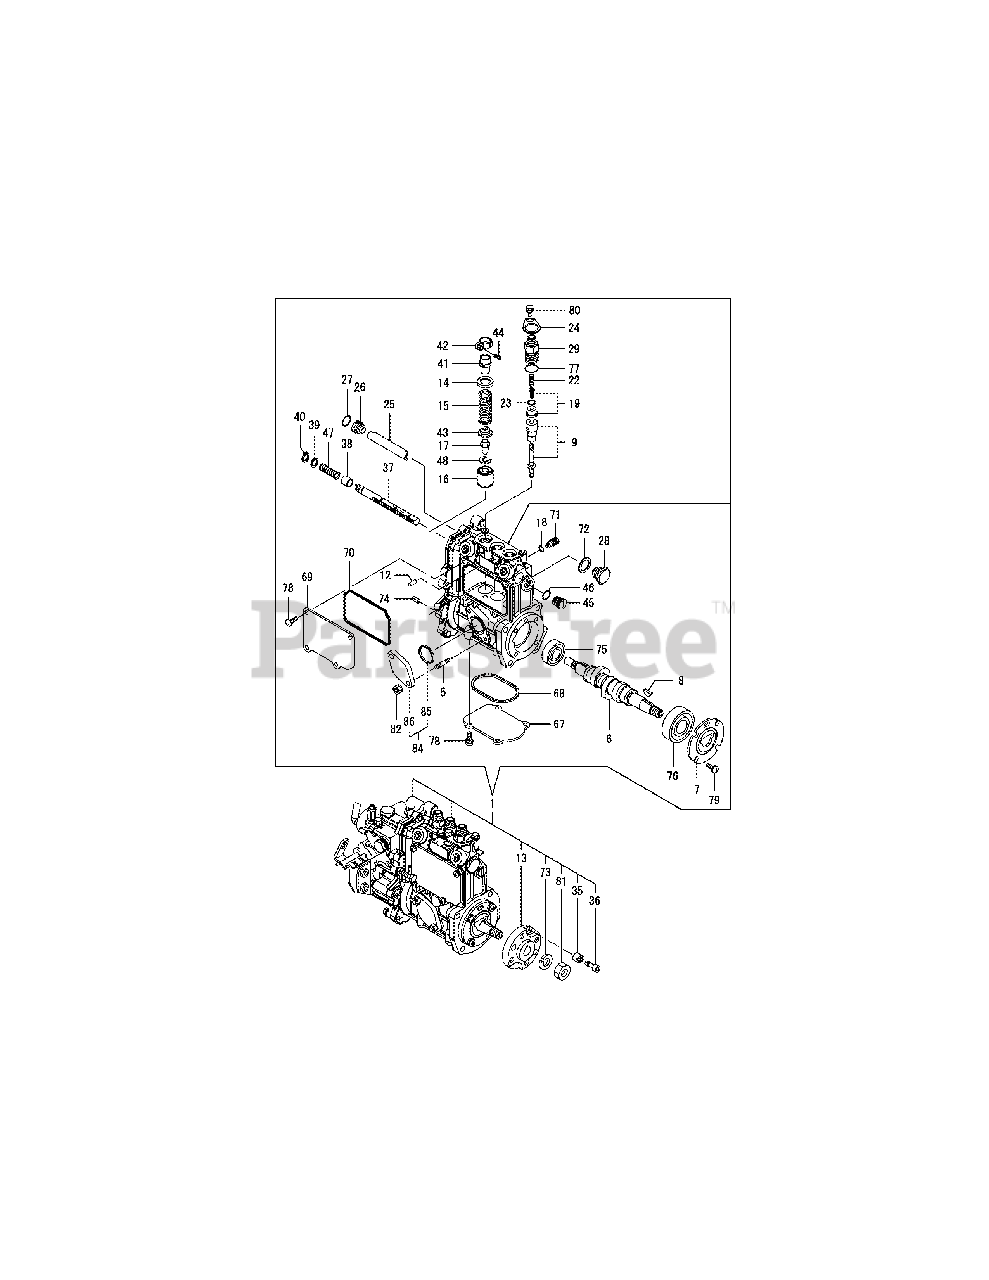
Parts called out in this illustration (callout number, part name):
1	INJECTION PUMP ASSY
5	STUD, FEED PUMP
12	PIN, BARREL LOCKING
14	RETAINER, SPRING
15	SPRING, PLUNGER
17	FO TAPPET GUIDE
19	VALVE ASSY, DELIVERY
22	SPRING, DELIVERY
23	GASKET, DELIVERY
26	PLUG, DEFLECTOR
28	PLUG, DEFLECTOR
29	VALVE ASSY, DELIVERY
35	COLLAR. FIC FIX
36	BOLT, FIXATION
39	SPACER, SPRING
41	PINION, CONTROL B
43	RETAINER, SPRING
48	SHIM SET, ADJUSTING
67	COVER, PUMP BOTTOM
68	GASKET, LOWER COVER
69	COVER, BODY SIDE
70	GASKET, SIDE COVER
73	SPRING WASHER 12
74	SPRING PIN 5X10
80	BOLT M 5X 10 PLATED
84	COVER ASSY, BLIND
